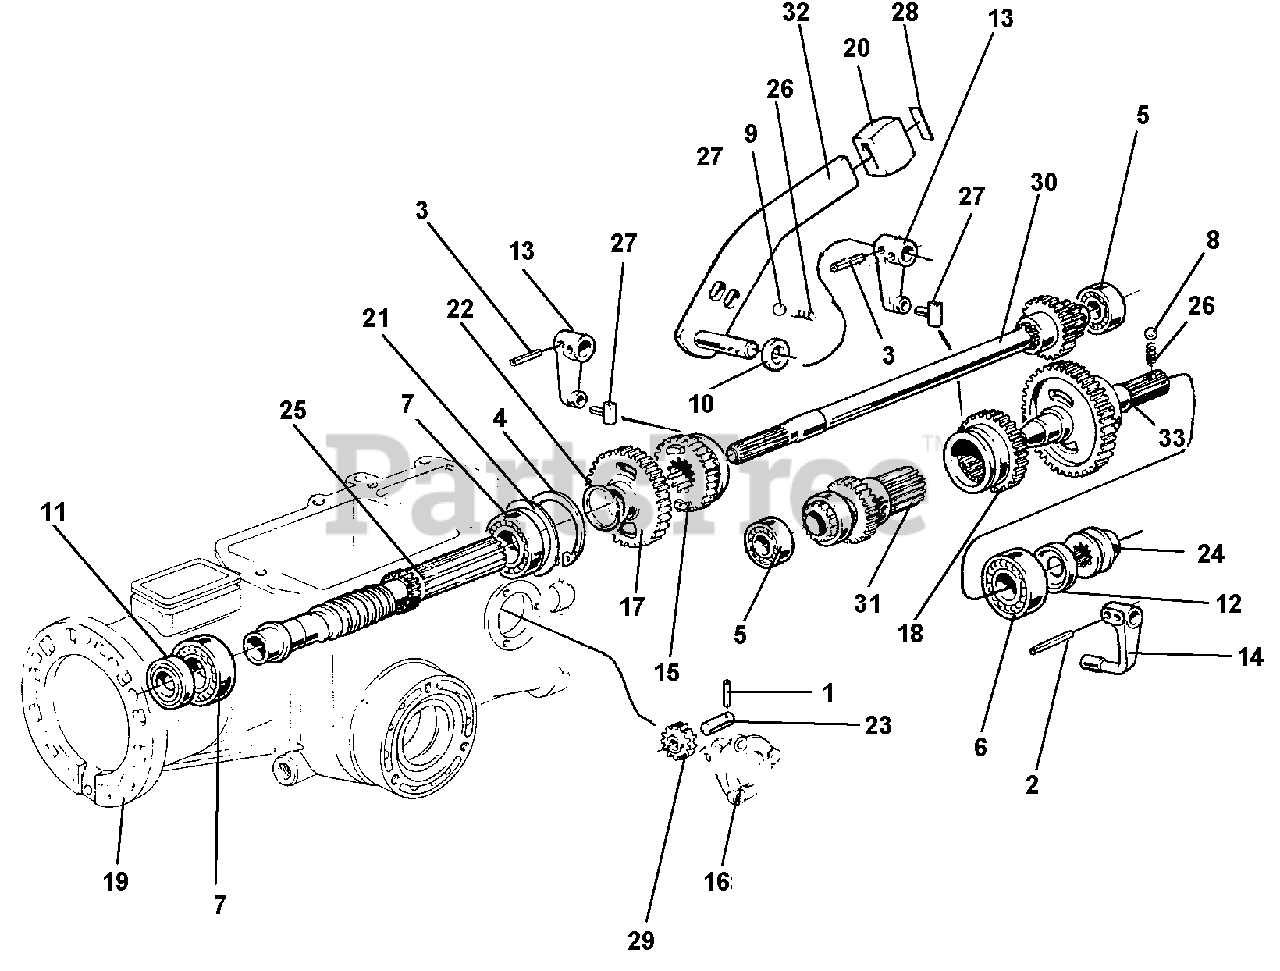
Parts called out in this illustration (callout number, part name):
1	PIN, LOCKING 2.5 X 22 DIN 1481
2	LOCKING PIN 4 X 20 SPIRAL
3	LOCKING PIN 4 X 24 SPIRAL
4	CIRCLIP, INTERN D 52
5	BEARING 15 X 35 X 11 6202
6	BEARING 20 X 47 X 14 6204
7	BEARING 25 X 52 X 15 6205
8	BALL 1/4 RIV RB-6.35
9	BALL 15/32 RIV RB-11.906
10	SEAL, OIL 12 X 19 X 5 STANDARD
11	SEAL, OIL 15 X 40 X 10 STANDARD
12	SEAL, OIL 20 X 35 X 7 STANDARD
13	LEVER, SPEED CHG SLDG GR
14	SLIDE LEVER
15	SLIDER SPEEDS
16	SLIDER REDUCTION UNIT
17	WHEELS FIRST SPEED
18	FLANGE, REVERSE SPEED
19	CASING 5 SPEEDS GEARBOX
20	KNOB REDUCTION UNIT LEVER
21	RING C - 72
22	WASHER 25 X 32 X 2 C - 72
28	DECAL SLOW/FAST SPEEDS
29	REVERSE SPEED GEAR
30	CLUTCH SHAFT
31	GEAR TRIPLE
32	LEVER REDUCTION UNIT
33	P.T.O. SHAFT
